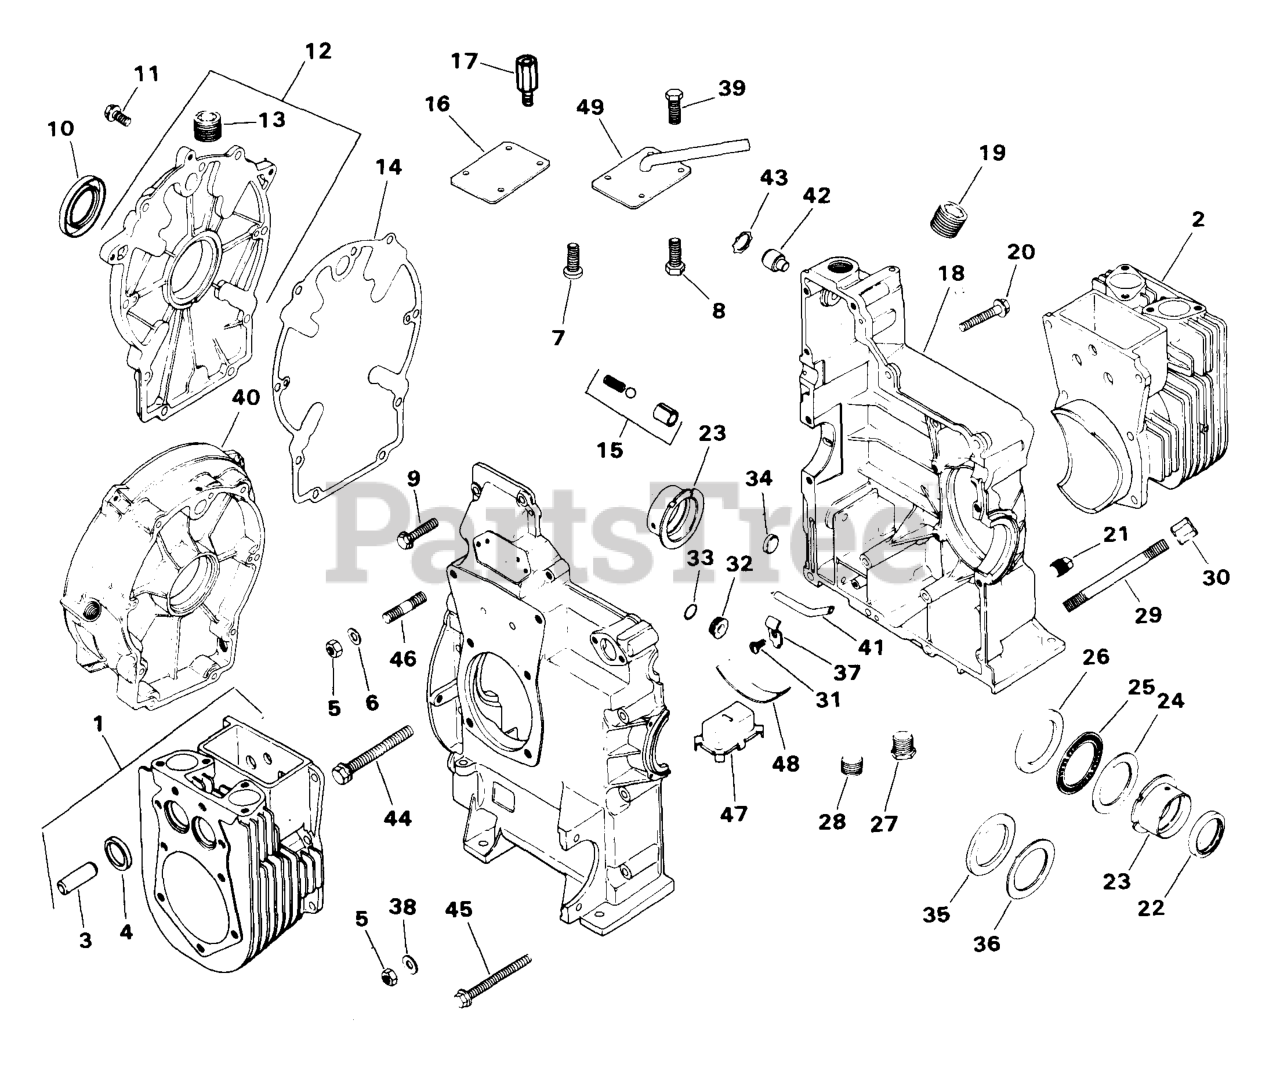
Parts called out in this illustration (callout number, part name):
1	Kit, Cylinder Barrel #1
2	Kit, Cylinder Barrel #2
3	Guide, Valve
4	Insert, Valve Seat
5	Nut, Hex. 5/16-18
6	Washer, Flat 5/16"
9	Screw, Hex. Flange 5/16-18x1-1/2"
10	Seal, Rear Oil 1-3/8" I.D.
11	Screw, Hex. Flange 5/16-18x1"
12	Kit, Closure Plate
13	Plug, Hex. Ctsk. 1/8" N.P.T.F.
15	Kit, Oil Relief
20	Screw, Hex. Flange 5/16-18x2"
21	Plug, Solid Sq. Hd. 3/8" N.P.T.F.
22	Seal, Front Oil
23	Bearing, Sleeve Flange (Std.)
23	Bearing, Sleeve Flange (.010)
23	Bearing, Sleeve Flange (.020)
28	Plug, Hex. Ctsk. 3/8" N.P.T.F.
31	Screw, Hex. Wash. Hd. 10-32x7/16"
32	Plug 3/4" O.D.
34	Plug, Cup 5/16"
37	Clamp, Tube
41	Tube, Oil Pickup
42	Shaft, Governor
43	Ring, Retaining
44	Screw, Hex. Flange 3/8-16x3-5/8"
45	Screw, Hex. Flange 5/16-18x3-1/2"
46	Step Stud 5/16-18x3/4", 3/8-16 X 5/8", 2" Long
47	Housing, Oil Strainer
48	Clamp, Spring
